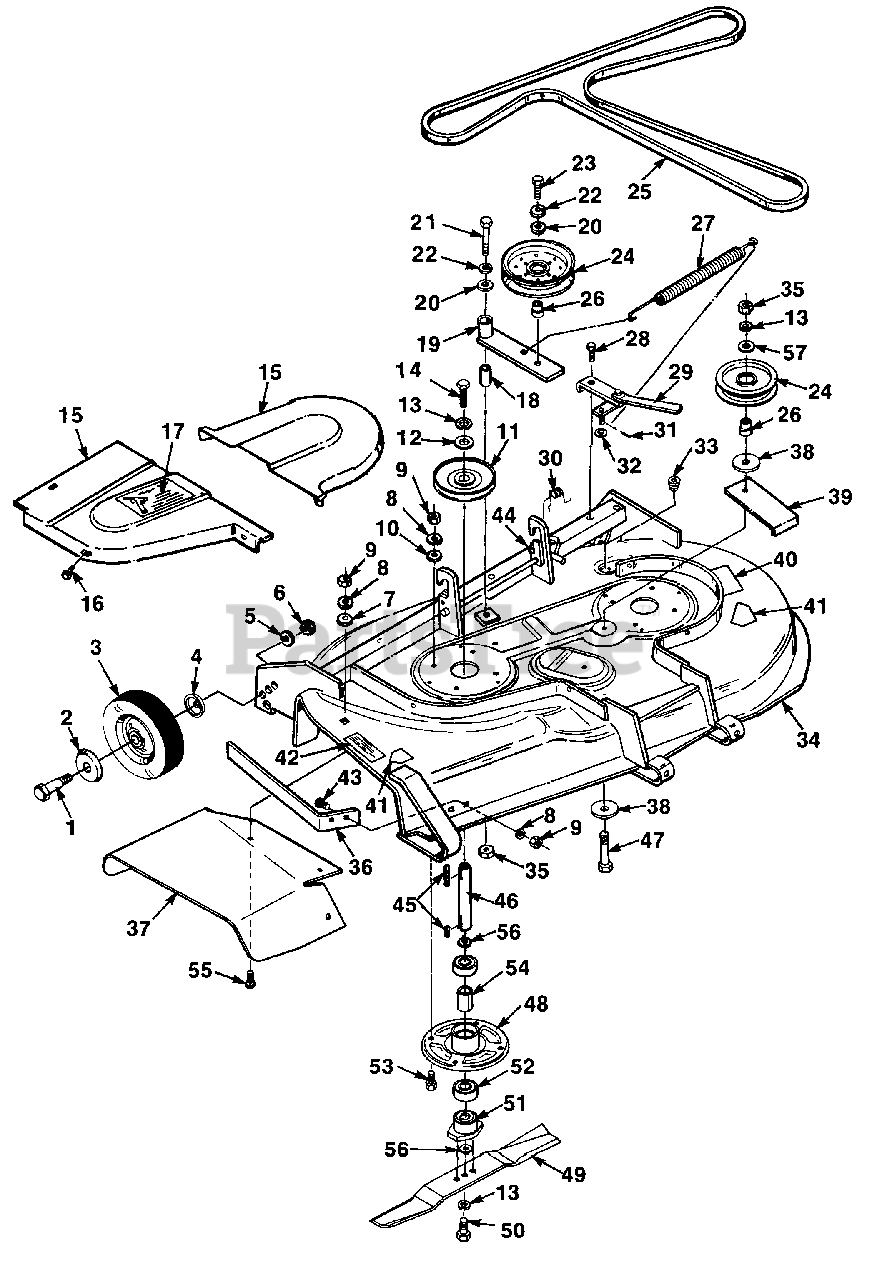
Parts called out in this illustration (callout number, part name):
3	TIRE ASSEMBLY
5	WASHER
7	WASHER
8	WASHER
9	NUT- Hex 5/16 x 18
11	PULLEY- R & L Drive
13	WASHER- 3/8 Lock
15	COVER- Belt (R.H.)
19	ARM ASSEMBLY
20	WASHER
22	WASHER
23	SCREW
25	BELT- Cutter drive
26	STAND-OFF
28	SCREW- 1/4-20 x 7/8
29	SPRING RELEASE ASSEMBLY
31	PIN- Cotter
32	WASHER- Plain 1/4
33	PLUG- Wash-Out
34	HOUSING- Mower
36	TOE GUARD
37	CHUTE- Extension
39	IDLER SUPPORT
41	DECAL- Warning
46	CUTTER SHAFT
47	SCREW
48	CUTTER HOUSING ASSEMBLY
49	BLADE- Cutter (set of 2)
51	ADAPTOR- Blade
53	SCREW
54	SPACER- Bearing
57	WASHER
